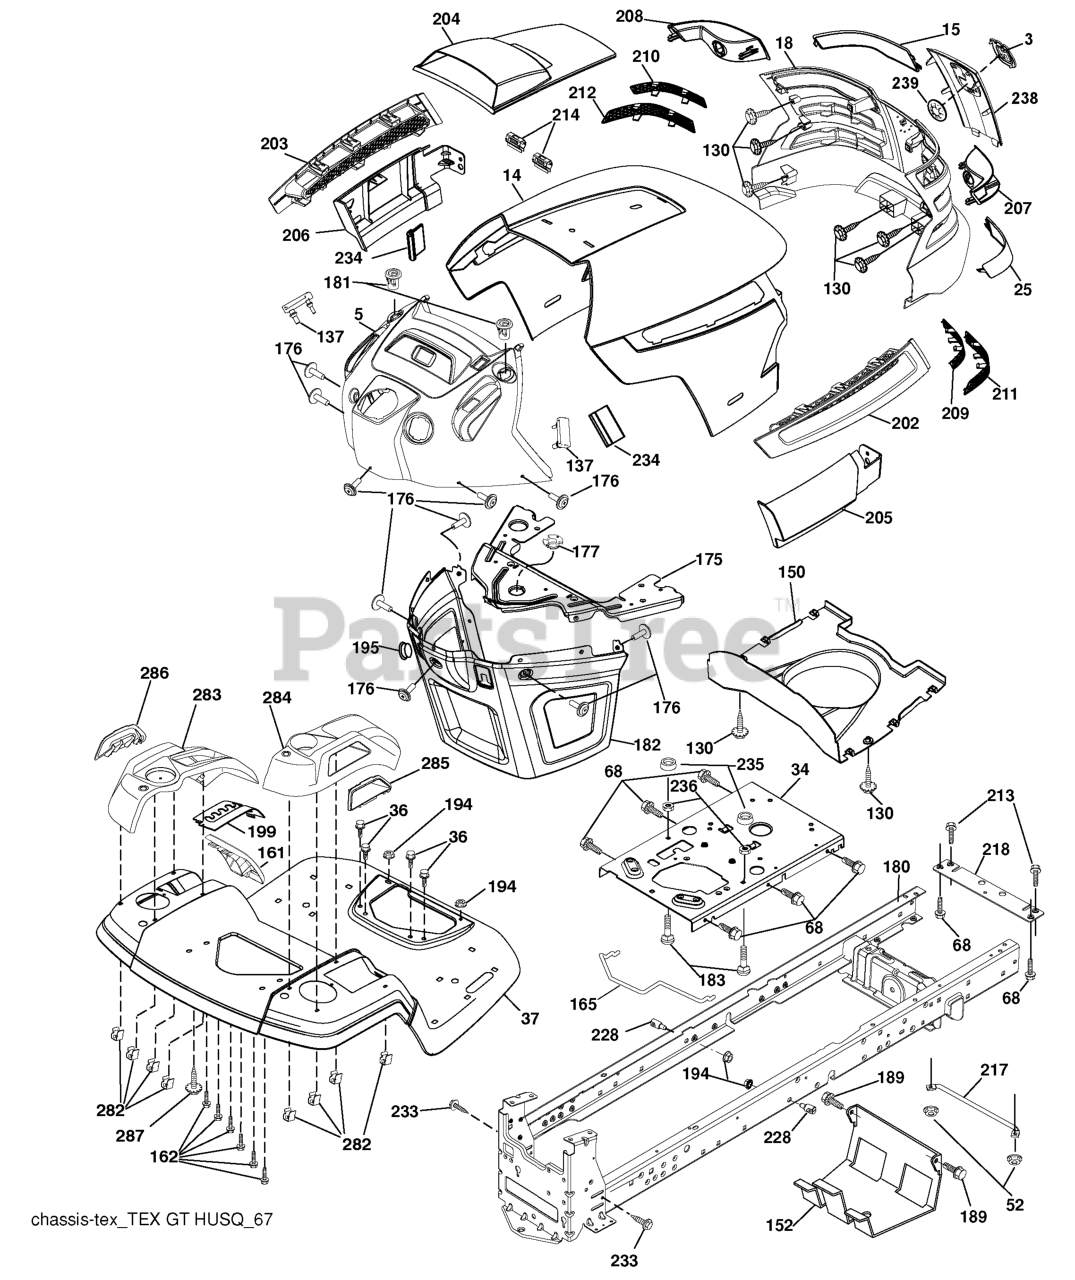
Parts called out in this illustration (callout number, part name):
3	RP LOGO
5	DASH.ASM.HUSQ.GT
14	HOOD
15	LENS.LH.TEX.GT.HUSQ.CL
18	GRILL.ASM.HUSQ.TG/CRD.W/TRIM
25	LENS.RH.TEX.GT.HUSQ.CL
34	PLATE.ENGINE.WELDED.CHASSIS
36	SCREW 5/16"
37	FENDER.TLT.FS.W/CPH/FW/RSF.ORN
52	LOCKNUT
68	Screw 5/16-18 x 1/2
130	SCREW.#10 X 0.750.BOS
137	BUMPER DASH
150	AIR.DUCT.HOOD.TEX.GT.HUSQ
152	SHIELD.BROWNING.W/TEX
161	WINDOW FUEL
162	SCREW.HI-LO.CONSOLE
165	SUPPORT.TANK.REAR.W/TEX
175	PLATE.CROSSMEMBER.HUSQ
176	SCREW.#10-24X5/8.RN.QU
177	BUSHING, STEERING
180	CHASSIS
181	BUSHING.MNT.FEND.CRGO.
182	DASH.LOWER.COMMON.12V.ADAPTOR
183	BOLT.5/16-18X1-1/4 FULL THD
189	SCREW
194	NUT LOCK HEX FLANGE 5/16-18
195	PLUG.HOLE.DASH.LOWER.12V.BLK
199	PLATE.DECK.LIFT.HUSQ.LT
202	VENT.SIDE.HOOD.HUSQ.RH.GREY
203	VENT.SIDE.HOOD.HUSQ.LH.GRAY
204	HOOD VENT
205	SKIRT.HOOD.SIDE.HUSQ.RH.GREY
206	SKIRT.HOOD.SIDE.HUSQ.LH.GREY
207	BEZEL.RH.TEX.GT.HUSQ
208	BEZEL.LH.TEX.GT.HUSQ
209	INSERT.HEX.GRILL.HUSQ.GREY
210	INSERT.HEX.GRILL.HUSQ.
211	INSERT.HEX.GRILL.HUSQ.
212	INSERT.HEX.GRILL.HUSQ.
213	BOLT
214	CLIP.RETAINER.TINNER.
217	ROD.PIVOT.HOOD
218	X-PIECE.HOOD.STOP.NON/
228	STUD.FASTNER.W/ANTI-ROTATE
233	BOLT.SHOULDER
234	BUMPER.HOOD.TEX.HUSQVARNA
235	SPACER FENDER
236	NUT.CENTERLOCK.5/16-
238	TRIM.HUSQ.TG/CRD.SERVICE
239	NUT PUSH M
282	CLIP.RETAINER.CONSOLE.LT.HUSQ
283	RP CONSOLE ASM.DECKLFT.RSF.
284	RP CONSOLE ASM.PDL CNTRL.HUSQ
285	CONSOLE INSERT RH
286	CONSOLE.INSRT.LH.HUSQ.LT.BLACK
287	SCREW 1/4X20
